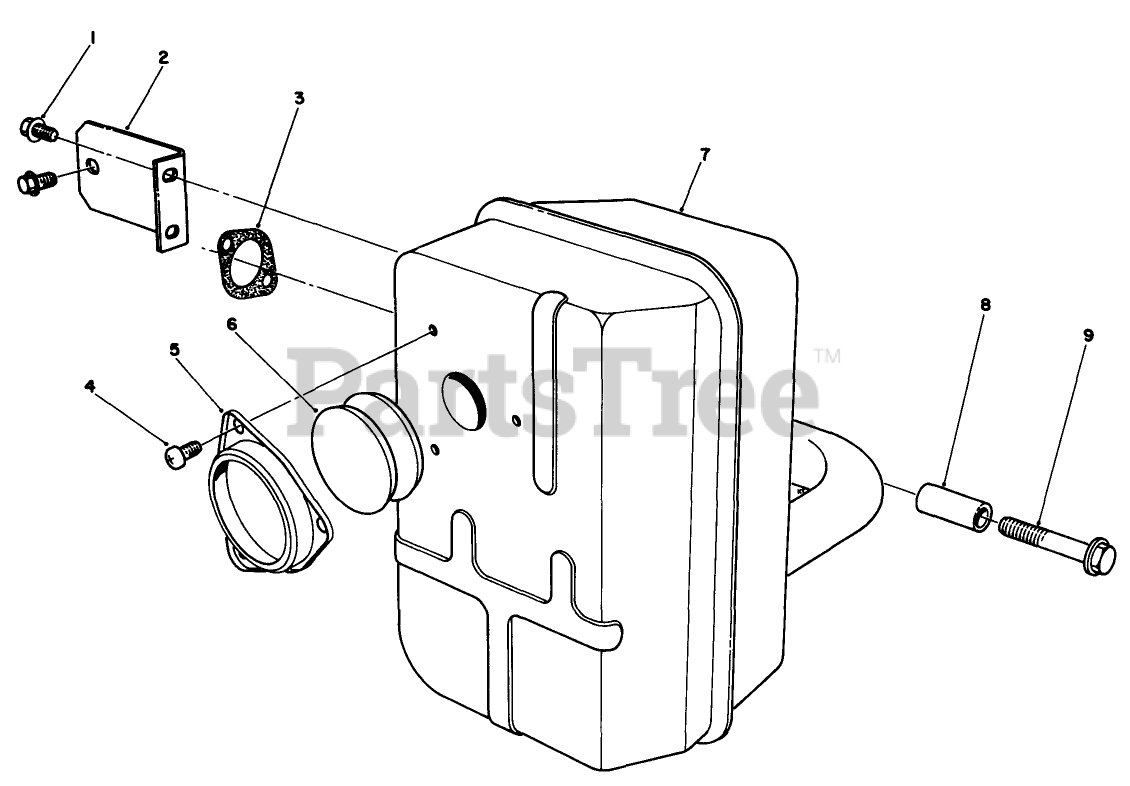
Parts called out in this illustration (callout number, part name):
1	Bolt-Flanged (8X12)
6	Arrester-Spark
7	Muffler Assembly (Incl. Ref.# 4,5 6)
9	Bolt-Flanged (8X45)
